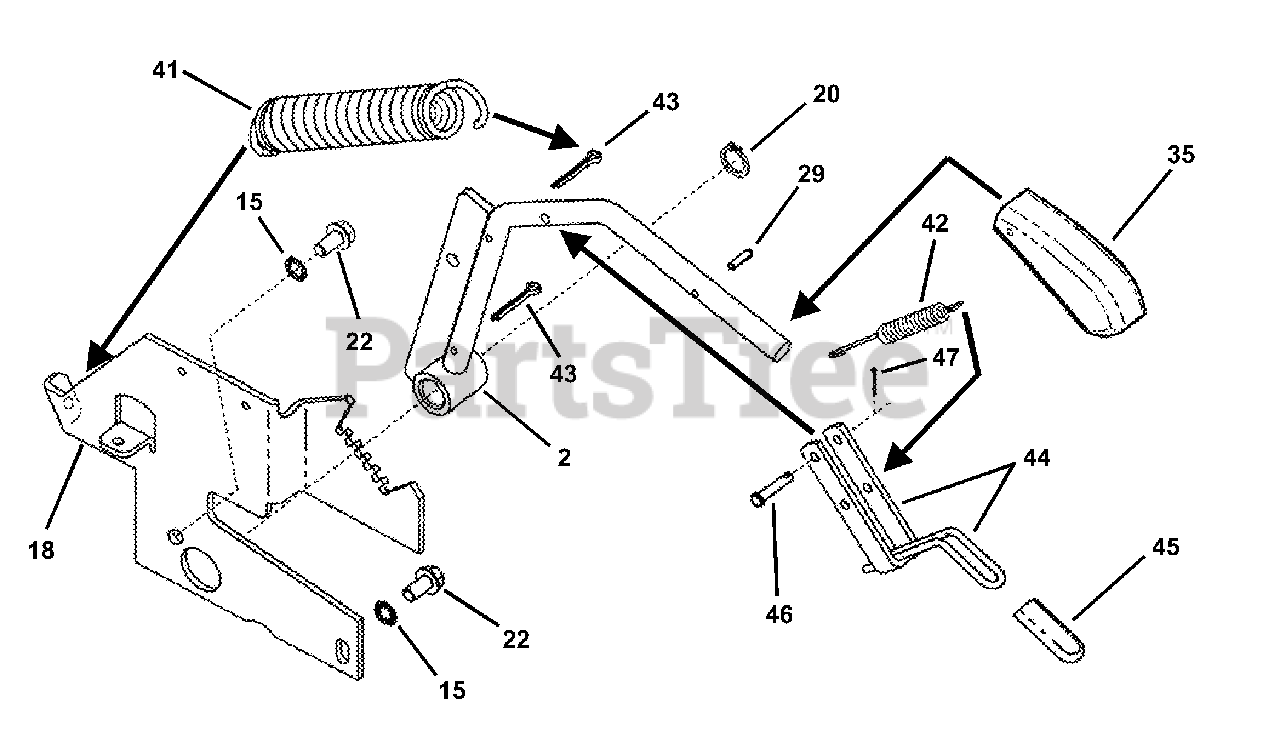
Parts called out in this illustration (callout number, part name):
2	LEVER, Height Adjustment Lift
15	WASHER, 3/8 Int. Tooth Lock
18	QUADRANT, Lift Lever
20	RING, 3/4 Retaining
22	SCREW, 3/8-16 x 3/4" Tap
29	PIN, 3/16 x 3/4" Roll
35	GRIP, Height Adjustment Lever
41	SPRING, Extension
42	SPRING, Latch
43	COTTER-PIN, 3/16 x 1-1/2"
44	LATCH Weldment
45	GRIP, Lift Latch
46	PIN, 1/4 x 1-1/4" Clevis
47	COTTER-PIN, 1/16 x 3/4"
